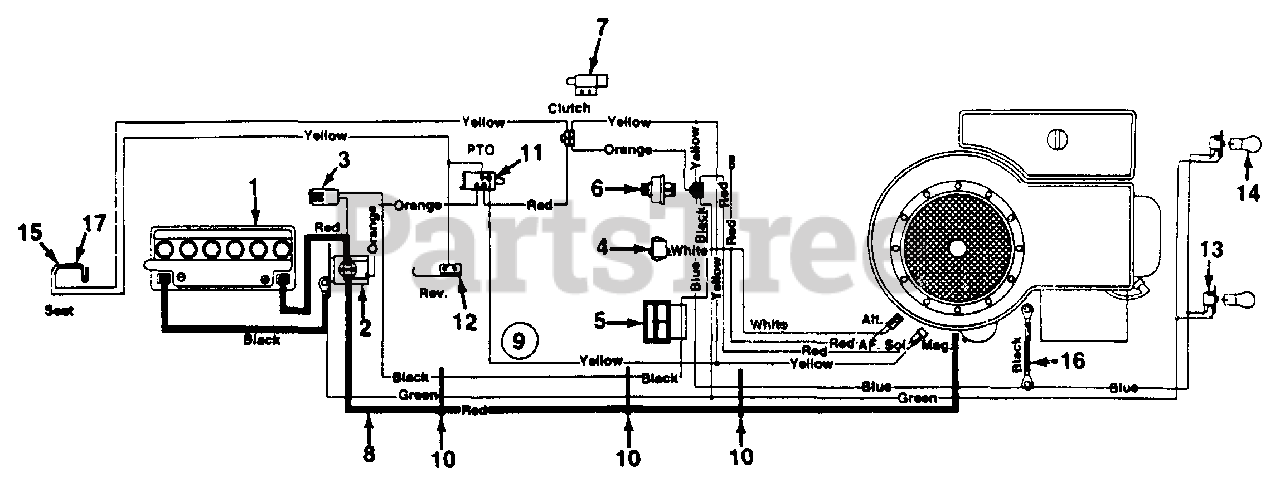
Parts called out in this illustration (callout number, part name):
1	Battery
2	Solenoid
3	Fuse 7.5 Amps
4	Light Switch
5	Ammeter
6	Ignition Switch
7	Safety Switch (Clutch)
8	Electric Wire 30" Lg.
9	Wire Harness w/Ammeter
10	Cable Tie
11	Safety Switch (Deck)
12	Safety Switch (Reverse)
13	Socket
14	Bulb (Headlight)
15	Safety Switch (Seat)
16	Ground Wire 7.5" Lg.
17	Safety Switch (Seat)
